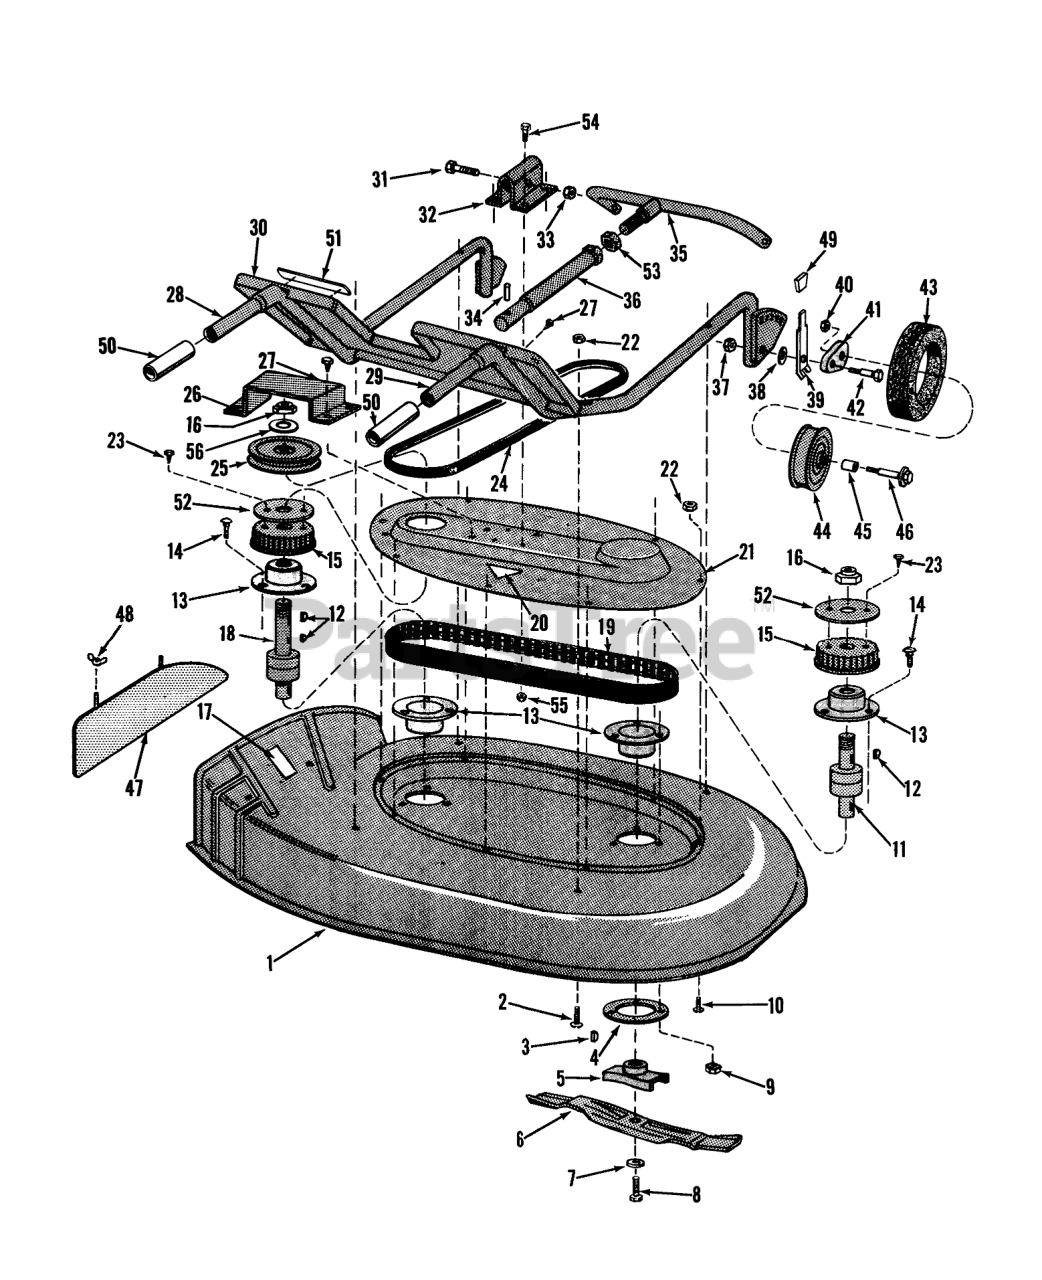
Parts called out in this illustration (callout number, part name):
1	Housing
4	Washer, Spindle
5	Retainer, Blade W.A.
6	Blade, 18"
7	WASHER-LOCK
8	Bolt. Place
9	NUT-KEPS
10	5/16-18X5/8 TRS HD MS
11	Bearing, Spindle
12	KEY-WOODRUFF
13	Housing, Bearing
14	Bolt
15	Pulley, P.D.
16	NUT-LOCK, NI
17	Decal
18	Bearing, Spindle
20	Decal
21	Shroud, Housing
22	NUT-LOCK, NI
23	SCREW-HWHTF
24	V-Belt
25	Pulley
26	Guard, Belt
27	10-16 X 3/8 THDG SCREW
28	Tube, Support W.A.
29	Tube, Support W.A.
30	Foot Rest
31	SCREW-HH
32	Bracket
33	NUT-LOCK, NI
34	PIN-ROLL, SLOTTED
35	Tube, Push W.A.
36	Tube, Tension W.A.
37	NUT-LOCK, NI
38	Washer
39	Spring Arm
40	NUT-HEX
41	Pivot Arm Assembly "A"
42	Pivot Screw
43	Tires, 6"
44	6" Wheel & Bushing Assy.
45	Bushing
47	Leaf Mulcher
48	NUT-WING SPECL
50	Sleeve
51	Tread Pad
52	Belt Guide
53	NUT-JAM
54	SCREW-HH
55	NUT-LOCK, NI
56	WASHER-FLAT
